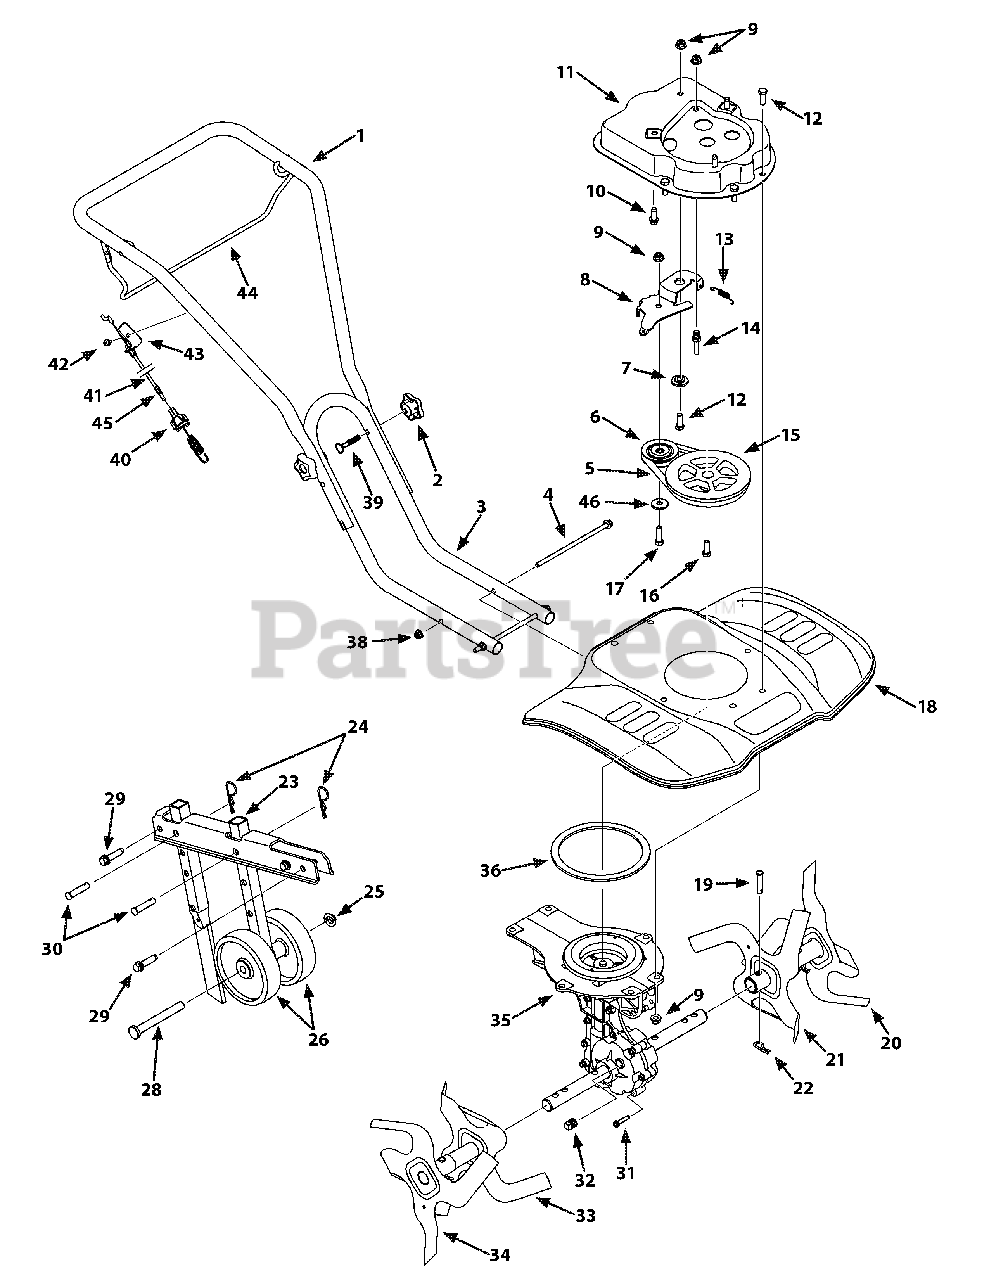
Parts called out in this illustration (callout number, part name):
2	Star Handle Knob
4	Flange Screwm 5/16-18:7.5 Gr 5
5	V- Belt
6	Idler Pulley
7	Shoulder Spacer
8	Idler Bracket
9	Flange Lock Nut, 3/8-16
10	TT Screw, 3/8-16:1.00
12	HH Cap Screw, 3/8-16:1.00
13	Extension Spring
14	Stud: 33 x 1.5 x 3/8-16
15	Flywheel Pulley
16	HH Cap Screw, 3/8-24:1.00
17	HH Cap Screw, 3/8-16:1.55
19	Clevis Pin
22	Internal Cotter Pin
24	Cotter Pin
25	Push Cap
26	Wheel 5 x 1.38
28	Axle Shaft
29	TT Screw, 3/8-16 x 1.50
30	Clevis Pin
31	TT Screw, 1/4-20:1.25
32	Pipe Plug, 3/8 NPT
35	Case Assembly
36	Gasket
38	Flange Lock Nut, 5/16-18
39	Carriage Bolt
40	Clutch Cable Fitting
41	Clutch Cable
42	TT Screw, 1/4-20:.50
45	Retaining Ring
46	Flat Washer, .406 x .875 x .059
